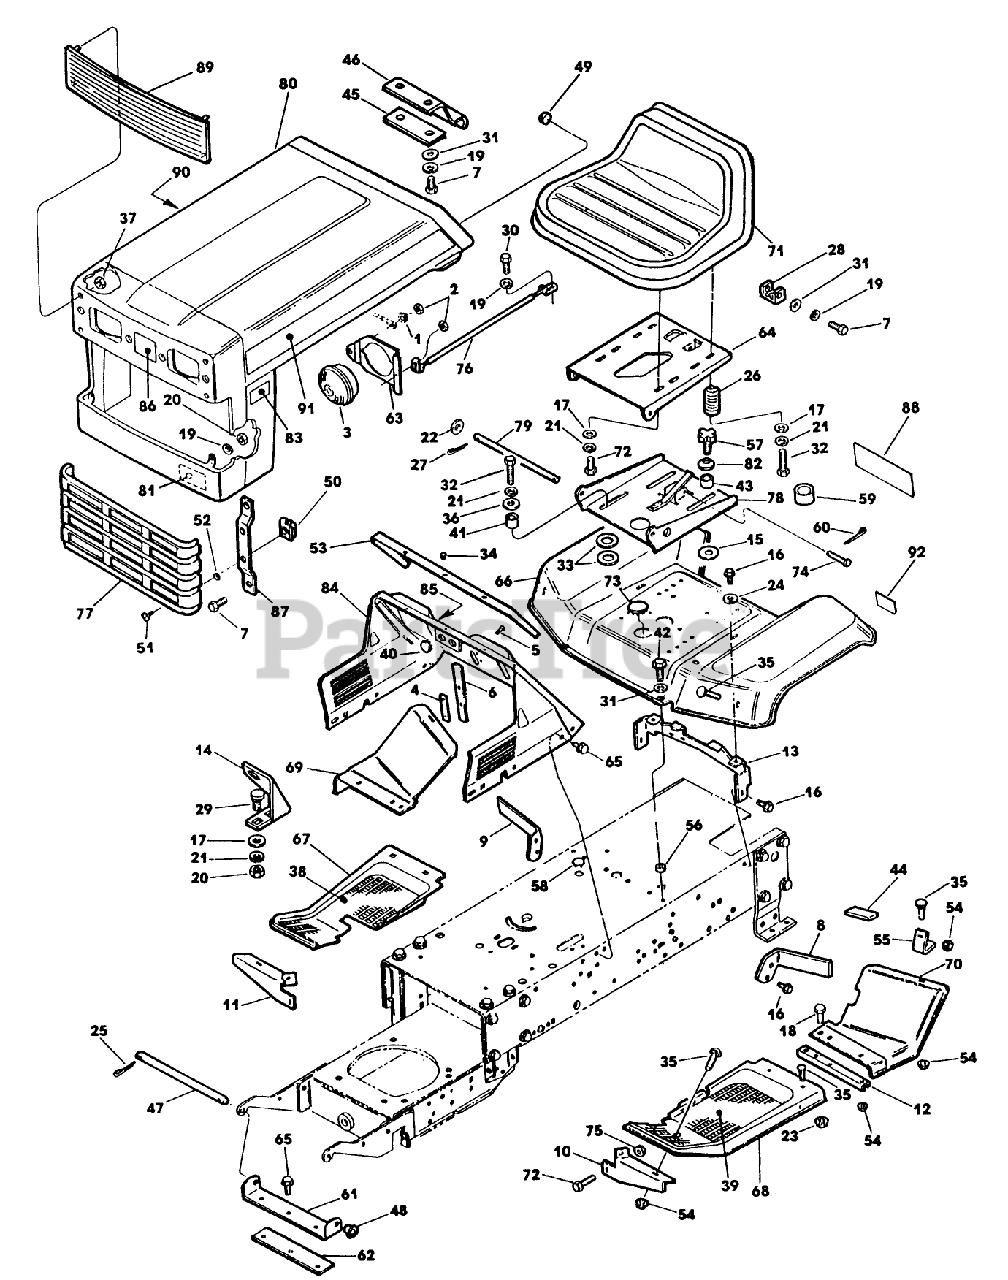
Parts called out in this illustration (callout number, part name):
7	SCREW-HH
13	BRACKET-SEAT SUPT
20	NUT
22	WASHER
30	SCREW
32	SCREW
33	WASHER-PLASTIC
43	SPACER
48	BEARING-NYLINER
51	FASTENER-1/4 TURN
57	KNOB
59	CAP-PROTECTOR
64	PIVOT AY - SEAT *B
72	SCREW - HEX
77	INSERT - GRILLE
78	SEAT SUPPORT AY
79	PIN
91	DECAL - HOOD LH
92	REFLECTOR
